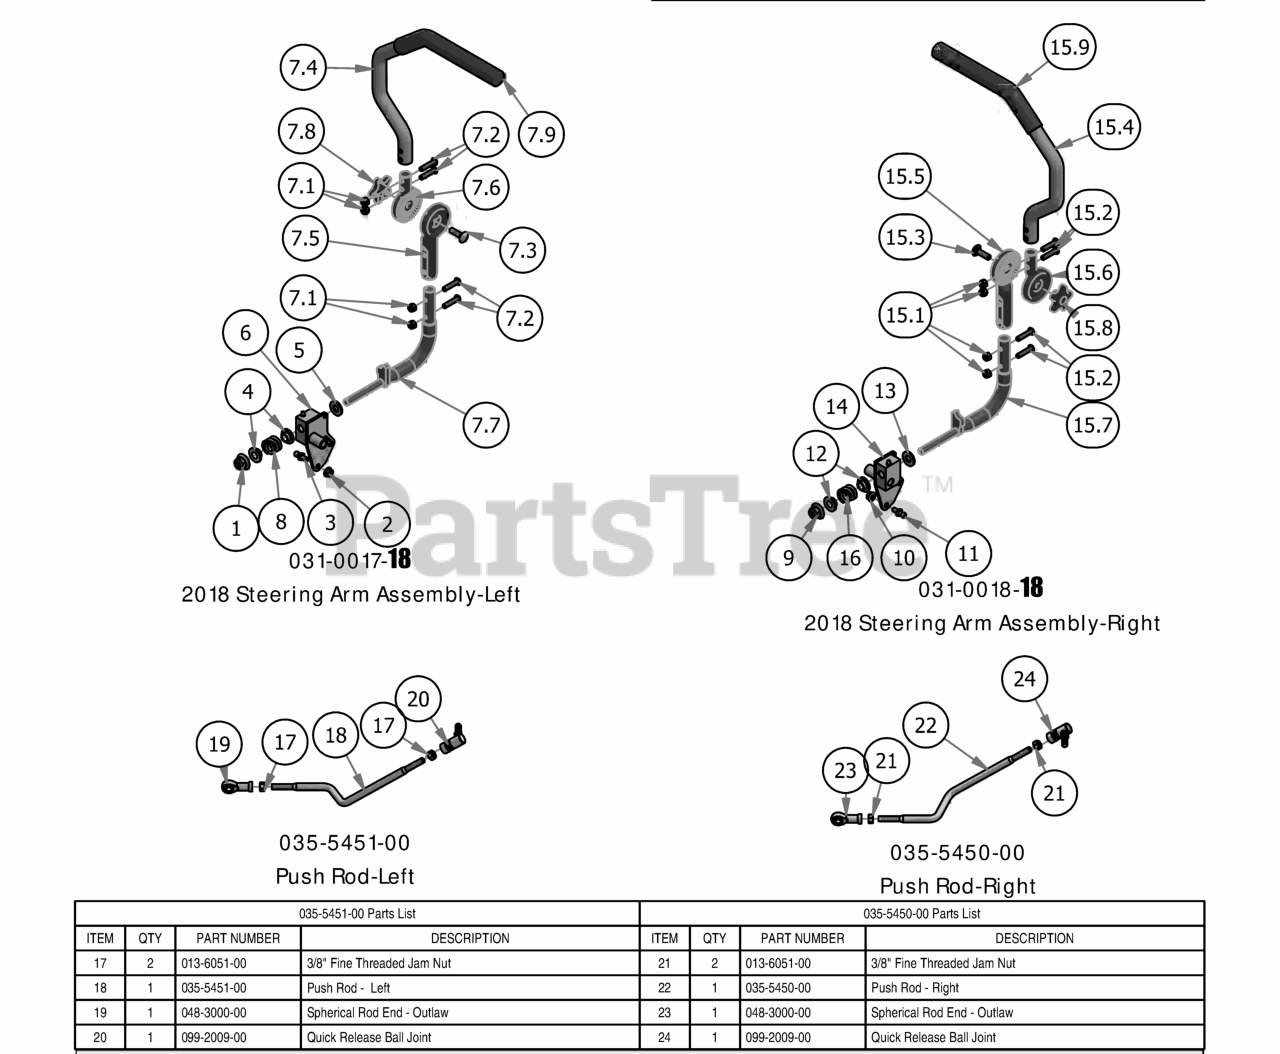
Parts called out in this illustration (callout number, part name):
1	1/2-13 Nylon Flange Nut
2	5/16" Flange Nut
3	10mm Damper Ball Stud-Steering
4	.515 ID Nylon Shoulder Washer
5	.505 Nylon Spacer
6	2017 Drive Lever Housing - Left
7	2018 Adjustable Steering Arm - Left
7.1	5/16-18 Nylock Insert Locknut
7.2	5/16-18 BHCS, TORX DRIVE
7.3	3/8" x 1 1/4" Carriage Bolt
7.4	Upper Tube-Adjustable Steering
7.5	2018 Lower Adjuster - Steering Arm- Left
7.6	2018 Upper Adjuster - Steering Arm- Left
7.7	Steering Arm Elbow (Left)
7.8	Black Knob for Adjustable Steering Arm
7.9	Rubber Grip
8	Drive Lever Spring
9	1/2-13 Nylon Flange Nut
10	5/16" Flange Nut
11	10mm Damper Ball Stud-Steering
12	.515 ID Nylon Shoulder Washer
13	.505 Nylon Spacer
14	2017 Drive Lever Housing - Right
15	2018 Adjustable Steering Arm - Right
15.1	5/16-18 Nylock Insert Locknut
15.2	5/16-18 BHCS, TORX DRIVE
15.3	3/8" x 1 1/4" Carriage Bolt
15.4	Upper Tube-Adjustable Steering
15.5	2018 Lower Adjuster - Steering Arm- Right
15.6	2018 Upper Adjuster - Steering Arm- Right
15.7	Steering Arm Elbow (Right)
15.8	Black Knob for Adjustable Steering Arm
15.9	Rubber Grip
16	Drive Lever Spring
17	3/8" Fine Threaded Jam Nut
18	Push Rod - Left
19	Spherical Rod End - Outlaw
20	Quick Release Ball Joint
21	3/8" Fine Threaded Jam Nut
22	Push Rod - Right
23	Spherical Rod End - Outlaw
24	Quick Release Ball Joint
